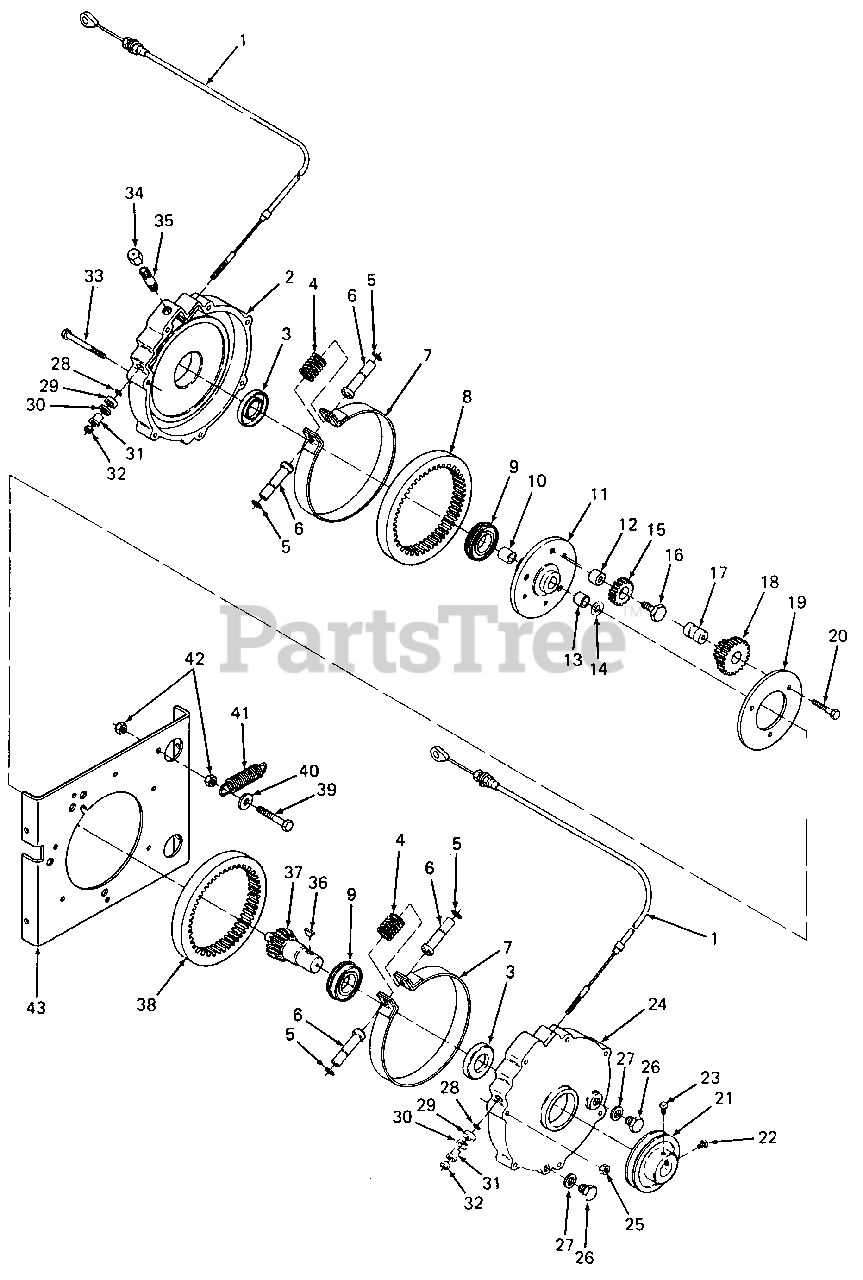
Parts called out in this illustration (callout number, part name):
1	Cable, Clutch
2	Housing, Rear Transmission
4	Spring, Clutch Return
6	Plunger, Clutch Band
7	Band, Clutch
8	Gear, Reverse Drive Ring
10	Plug, Transmission
12	Bushing, Orbit Gear Short
13	Bushing, Transmission
14	Race, Thrust (.060 Thk)
15	Gear, Reverse Orbit
16	Bolt, Reverse Idler
17	Bushing, Orbit Gear Long
18	Gear, Cluster
19	Plate, Support
20	Screw, Hex Cap, 3/8-16 X 1.75 Lg GR8
22	Setscrew, 5/16-18 X 1/2 Lg
23	Setscrew, 5/16-18 x 3/8 Lg
24	Housing, Front Transmission
25	Nut, Hex Center Lock, 5/16-18
26	Plug, Drain
27	Washer, Nylon
29	Washer, Cable
30	Spring, Cable Washer
31	Guide, Cable Seal
32	Nut, Hex, 1/4-20
33	Screw, Hex Cap, 5/16-18 X 3.00 Lg GR2
34	Cap (Vented) Pipe
35	Nipple, Pipe, 1/4-18 X 1.5 Lg
36	Key, Hi-Pro, 1/4 X 3/4
37	Shaft, Input
38	Gear, Forward Drive Ring
39	Screw, Hex Cap, 3/8-16 X 2.25 Lg GR5
40	Washer, Flat, .385 X .87 X .06 Thk
41	Spring, Idler (Extension)
42	Nut, Hex Center Lock, 3/8-16
43	Bulkhead, Transmission
